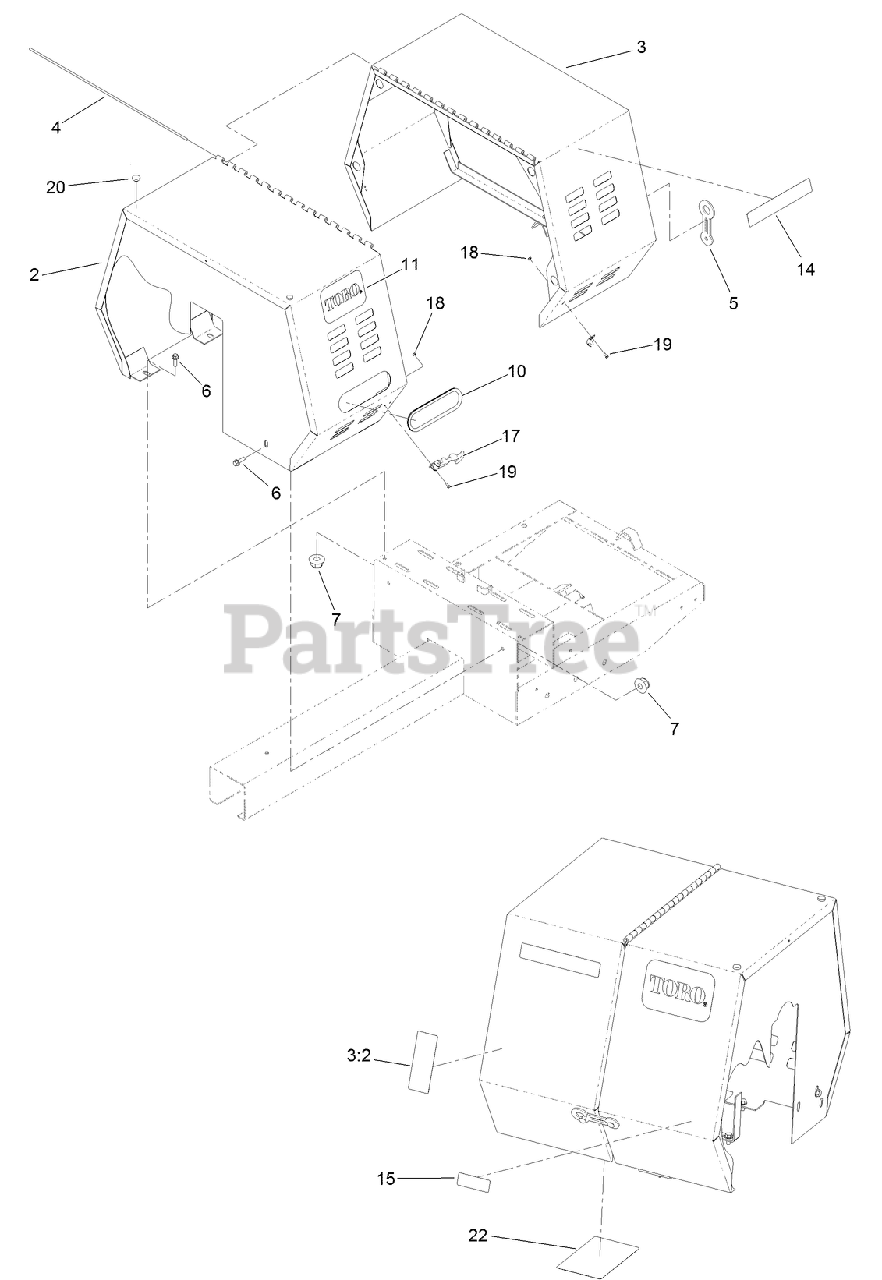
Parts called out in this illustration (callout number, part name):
2	STATIONARY COWL ASM
3	MOVABLE COWL ASM
3:2	DECAL-WARNING
5	LATCH-RUBBER
6	SCREW-HHF
7	NUT-HF, NI
10	TRIM-LID
11	DECAL
15	DECAL-ARRESTER, SPARK
17	LATCH-FLEX, DRAW
18	NUT-LOCK, NI
19	SCREW-HWH
20	BUMPER
22	DECAL-SERVICE
